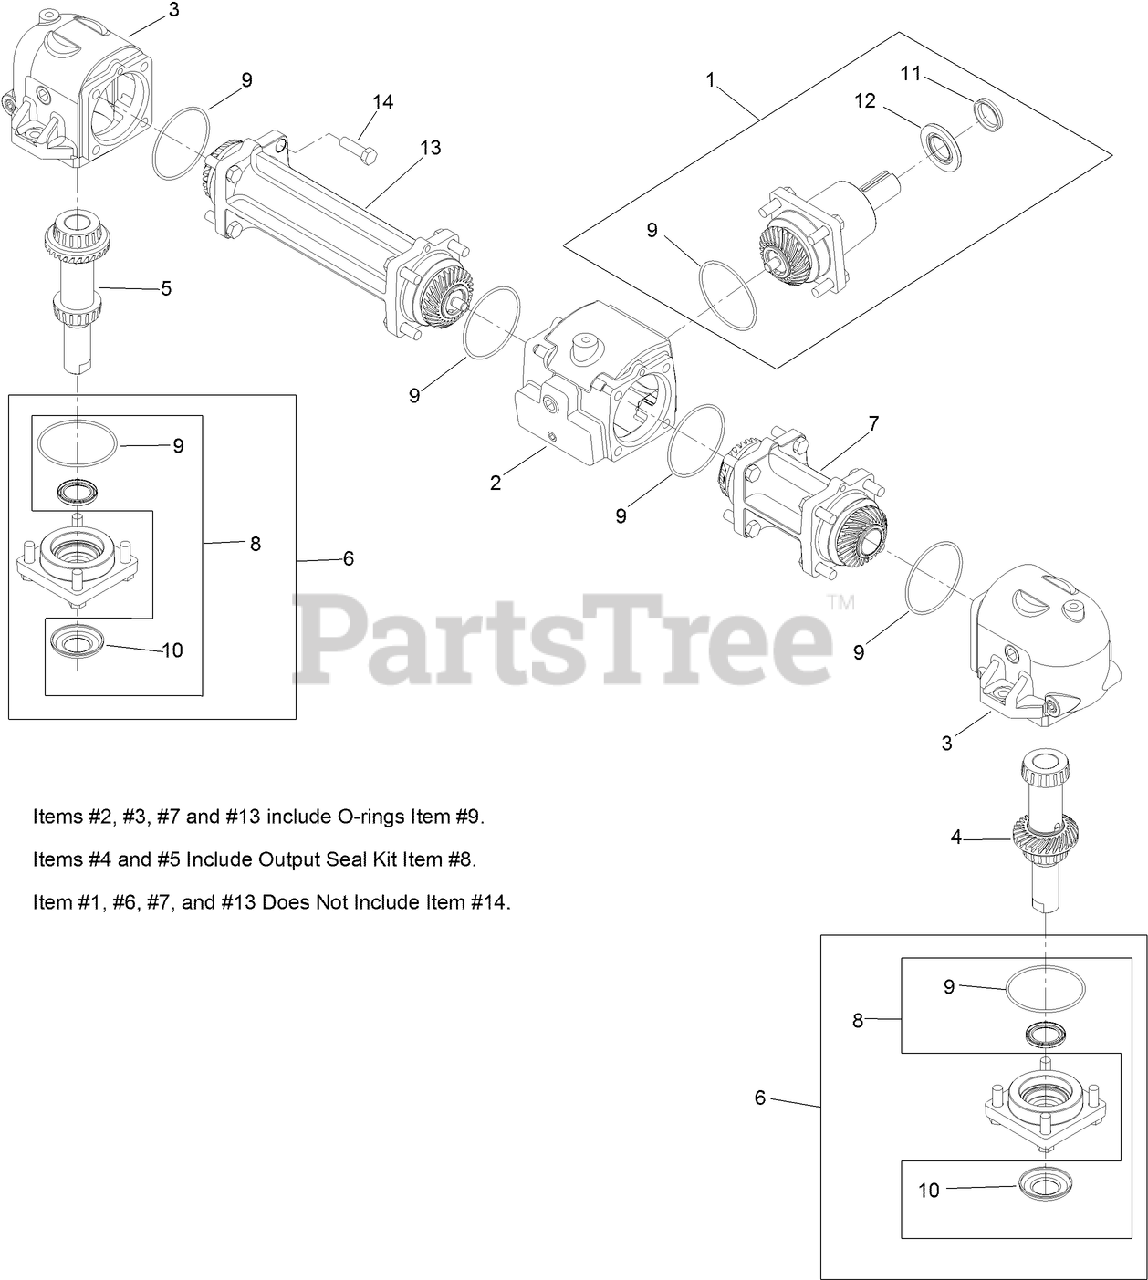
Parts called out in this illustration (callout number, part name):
1	PINION-INPUT
2	HOUSING-CENTER
3	HOUSING-END
4	OUTPUT SHAFT AND GEAR-LH
5	OUTPUT SHAFT AND GEAR-RH
6	CAP-OUTPUT
7	TUBE-CONNECTOR, SHOR
8	OUTPUT SEAL KIT
9	SEAL-O-RING
10	WASHER-CUPPED
11	SEAL-V-RING
12	SEAL-INPUT
13	CONNECTOR-TUBE, LONG
14	BOLT-BLADE
